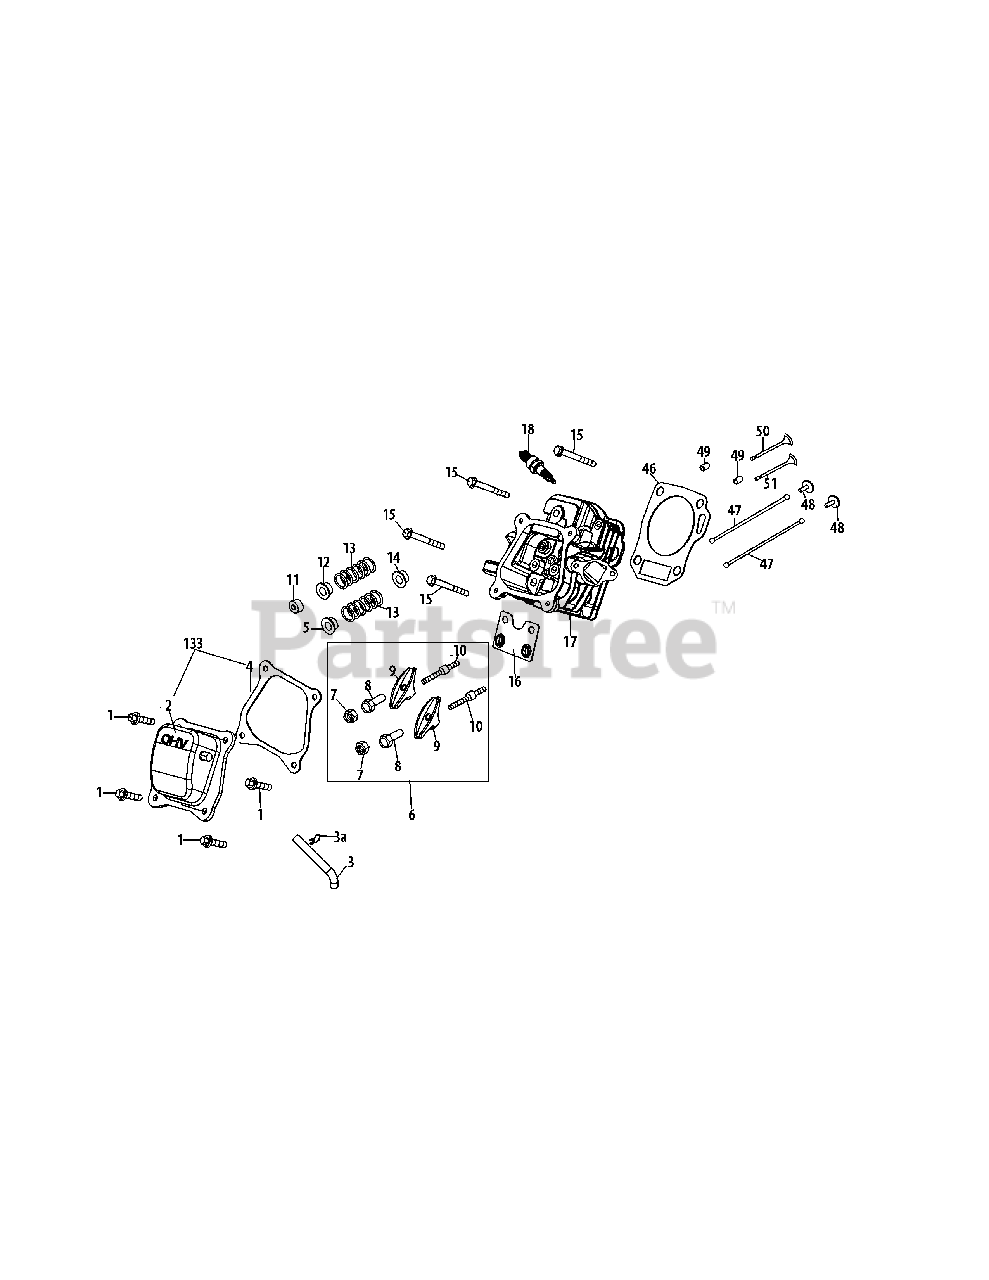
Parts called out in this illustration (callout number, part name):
1	Bolt M6×16
2	Valve Cover
3	Breather Hose
4	Valve Cover Gasket
5	Retainer, In.Valve Spring
6	Rocker Arm Assembly
7	Nut, Pivot Locking
8	Adjusting Nut ,Valve
9	Rocker Arm
10	Bolt, Pivot
11	Adjuster, Exh Valve
12	Retainer, Ex.Valve Spring
13	Valve Spring
14	Intake Valve Seal
15	Bolt M8×55
16	Push Rod Guide
17	Cylinder Head Assembly
18	Spark Plug/F6Rtc
46	Gasket, Cylinder Head
47	Push Rod Kit
48	Tappet
49	Dowel Pin, 10×16
50	Valve Kit
51	Valve Kit
133	Valve Cover Kit
